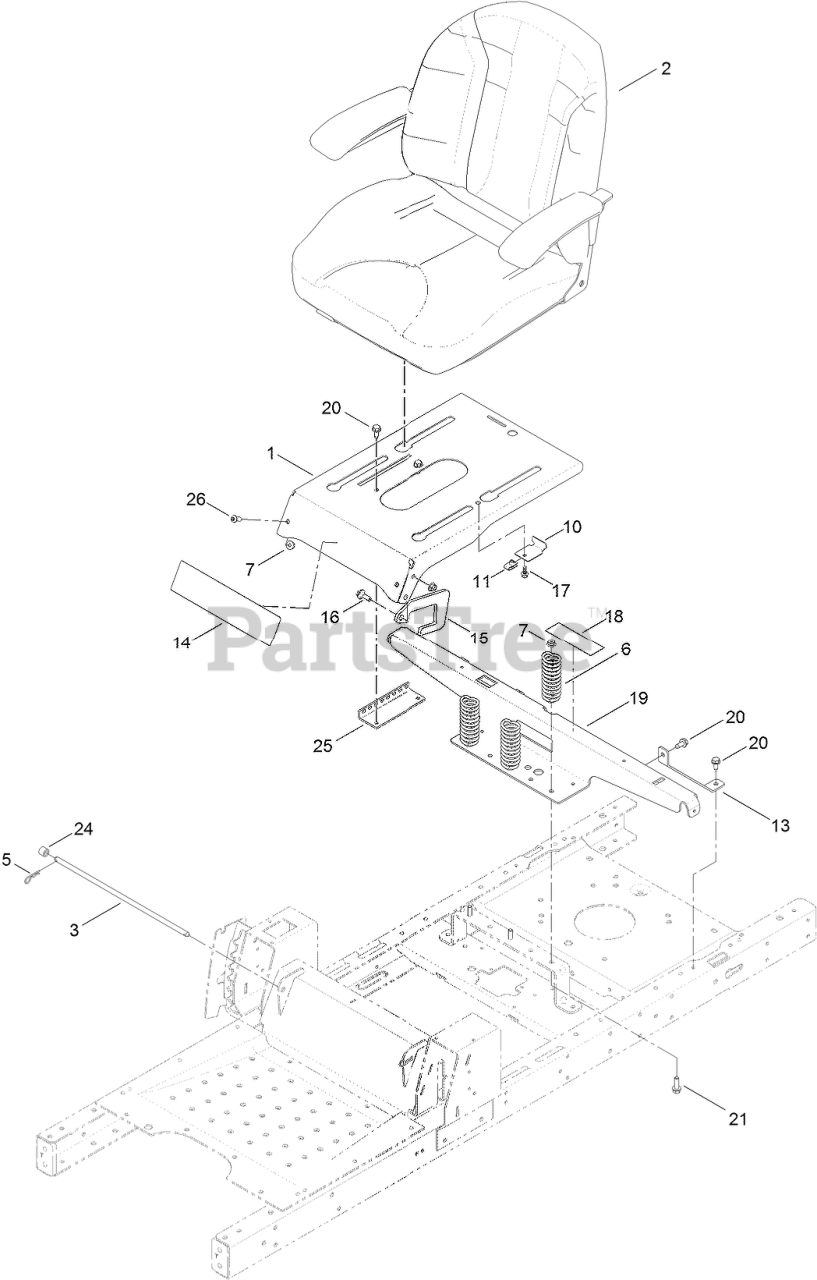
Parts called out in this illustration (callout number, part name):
1	PAN-SEAT
2	SEAT ASM
3	ROD-STOP
5	PIN-COTTER
6	SPRING-COMPRESSION
7	NUT-HF, NI
10	BRACKET-STOP, SEAT
13	SUPPORT-TANK, REAR
14	DECAL-TIMECUTTER
15	PLATE-STOP
16	SCREW-SHOULDER
17	SCREW-HHF
18	DECAL-SERVICE, CE
19	SUPPORT-POD, WIDE
20	SCREW-HWHTF
21	SCREW-HHF
24	BUSHING-LEVER, LIFT
25	BRACKET-LATCH, SEAT
26	SCREW-HSBH
